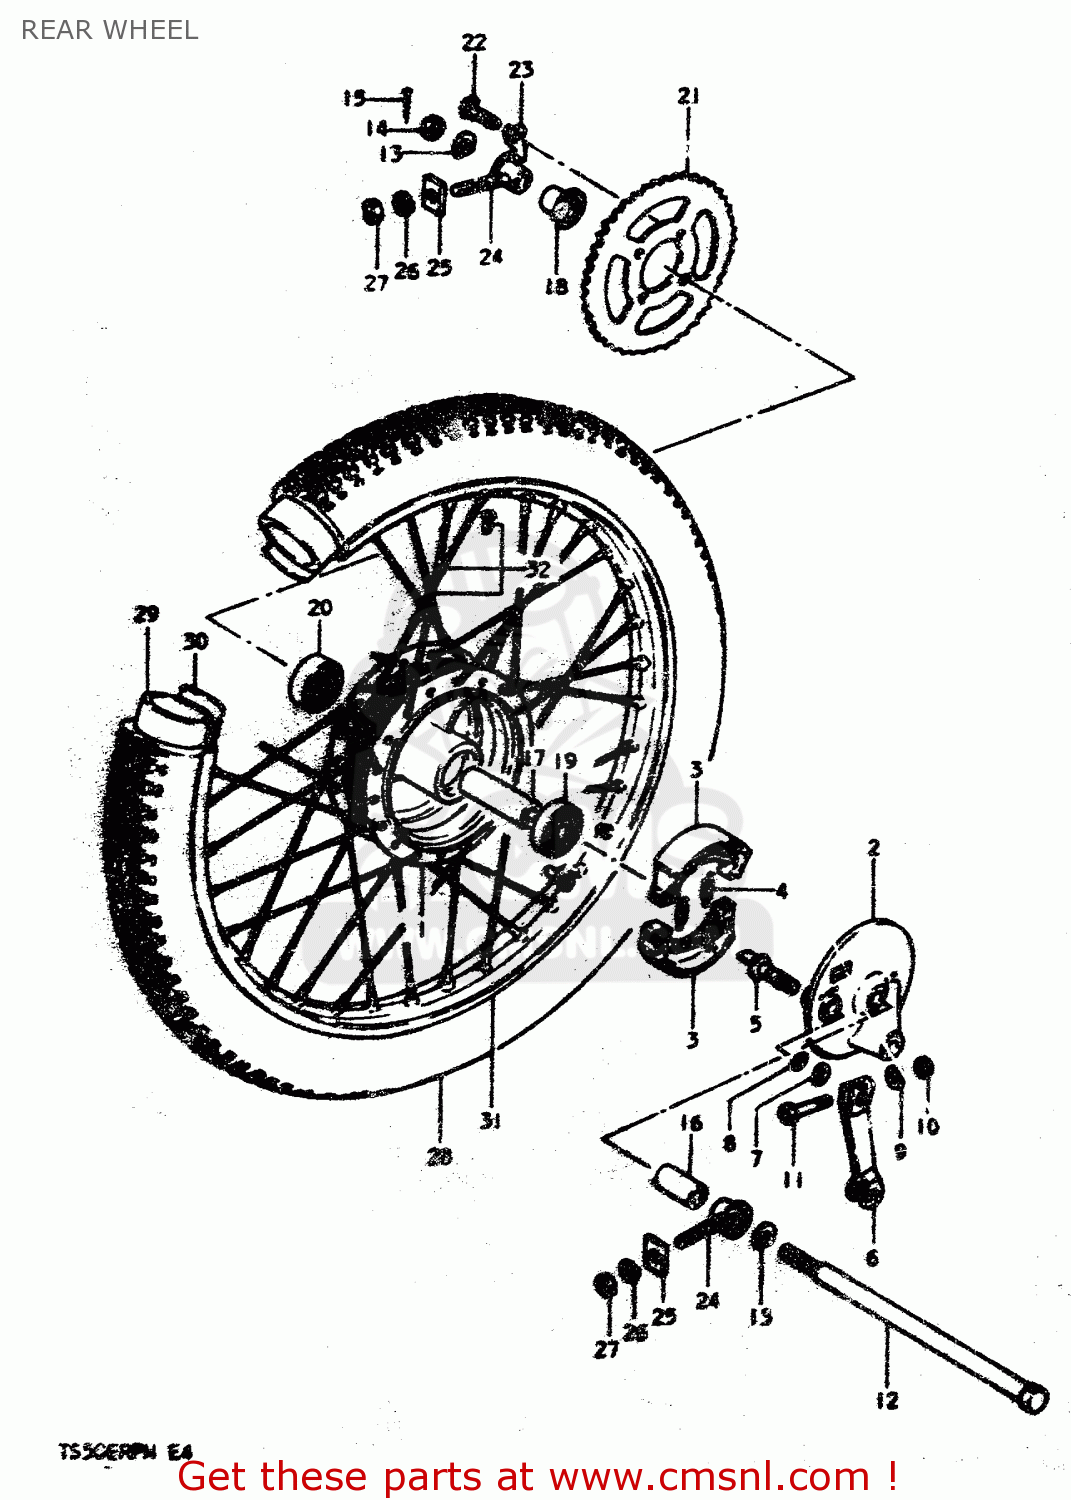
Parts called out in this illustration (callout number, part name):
1	DRUM, REAR HUB
2	PANEL,REAR BRAKE ANCHOR
3	SHOE,BRAKE
4	SPRING(L:34)
5	CAM,FRONT BRAKE
6	LEVER,RR BRAKE CAM
7	WASHER (14.5X22X1.6)
8	O-RING (D:2.4 ID:13.8)
9	WASHER
10	NUT
11	BOLT(6X33)
12	AXLE,RR
13	WASHER,RR AXLE
14	NUT 12MM
15	COTTER PIN
16	SPACER, AXLE RH
17	SPACER(12.6X19X91)
18	SPACER, REAR AXLE LH
19	BEARING
20	BEARING
21	SPROCKET, REAR (NT:47)
22	BOLT(8X25)
23	WASHER
24	ADJUSTER, CHAIN
25	ADJUSTER,CHAIN
26	LOCK WASHER
27	NUT
28	TIRE (3.00-17)
29	TUBE,INNER (IRC)
30	PROTECTOR,WHEEL,INNER
31	RIM,RR WHEEL(17X1.60)
32	SPOKE SET,REAR
